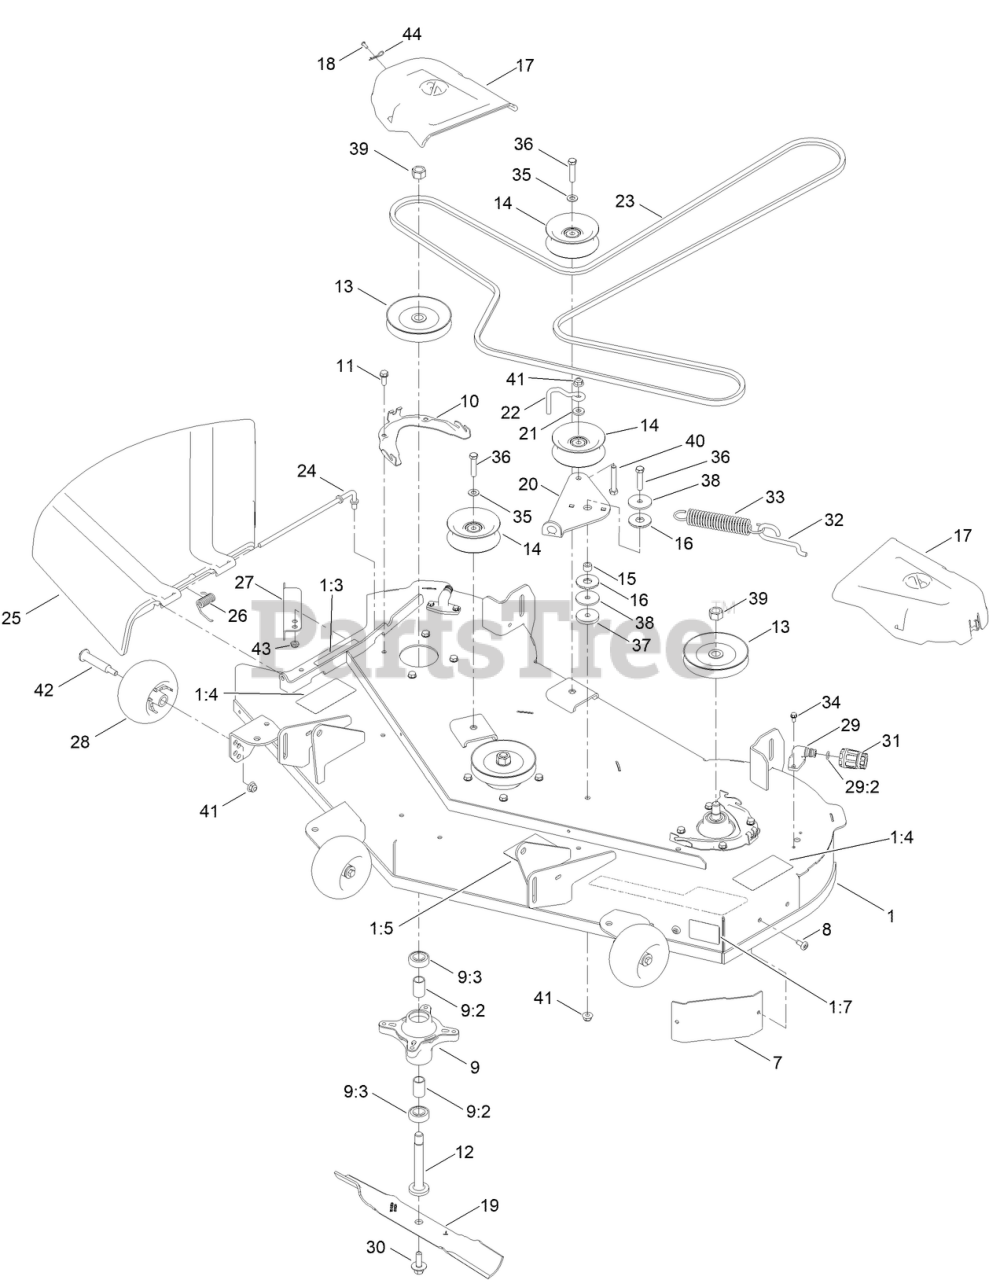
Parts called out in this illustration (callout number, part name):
1	50 IN DECK DECAL ASM
1:3	DECAL-DANGER
1:4	DECAL-DANGER, DECK
1:5	DECAL-ROUTING, BELT
1:7	DECAL-SCALP, ANTI
7	BAFFLE-CORNER
9	SPINDLE ASM
9:2	SPACER
9:3	BEARING-BALL
10	BRACKET-COVER, BELT
11	SCREW-TAPTITE
12	SHAFT-SPINDLE
13	PULLEY
14	PULLEY-IDLER, FLAT
15	SPACER
16	WASHER-FRICTION, COMPOSITE
17	COVER-BELT
18	SCREW
19	BLADE-HI LIFT
20	ARM-IDLER
21	SPACER-HUB, BLOWER
22	BELT GUIDE - IDLER
23	V BELT (A SEC 142.06 EL)
24	ROD-PIVOT
25	DEFLECTOR-DISCHARGE
26	SPRING-TORSION
27	BAFFLE-CUTOFF
28	ROLLER-SCALP, ANTI
29	FITTING-WASHOUT
29:2	O-RING
30	BOLT-BLADE, SEMS
31	CONNECTOR-HOSE
32	HOOK-RETURN SPRING
33	SPRING-EXTENSION
34	SCREW-HWH
35	WASHER-FLAT
36	SCREW-HH
37	WASHER-PLAIN
38	WASHER-REBOUND
39	NUT-HEX
40	SCREW-HH
41	NUT-HF, NI
42	BOLT-SHOULDER
44	PIN-HAIR
